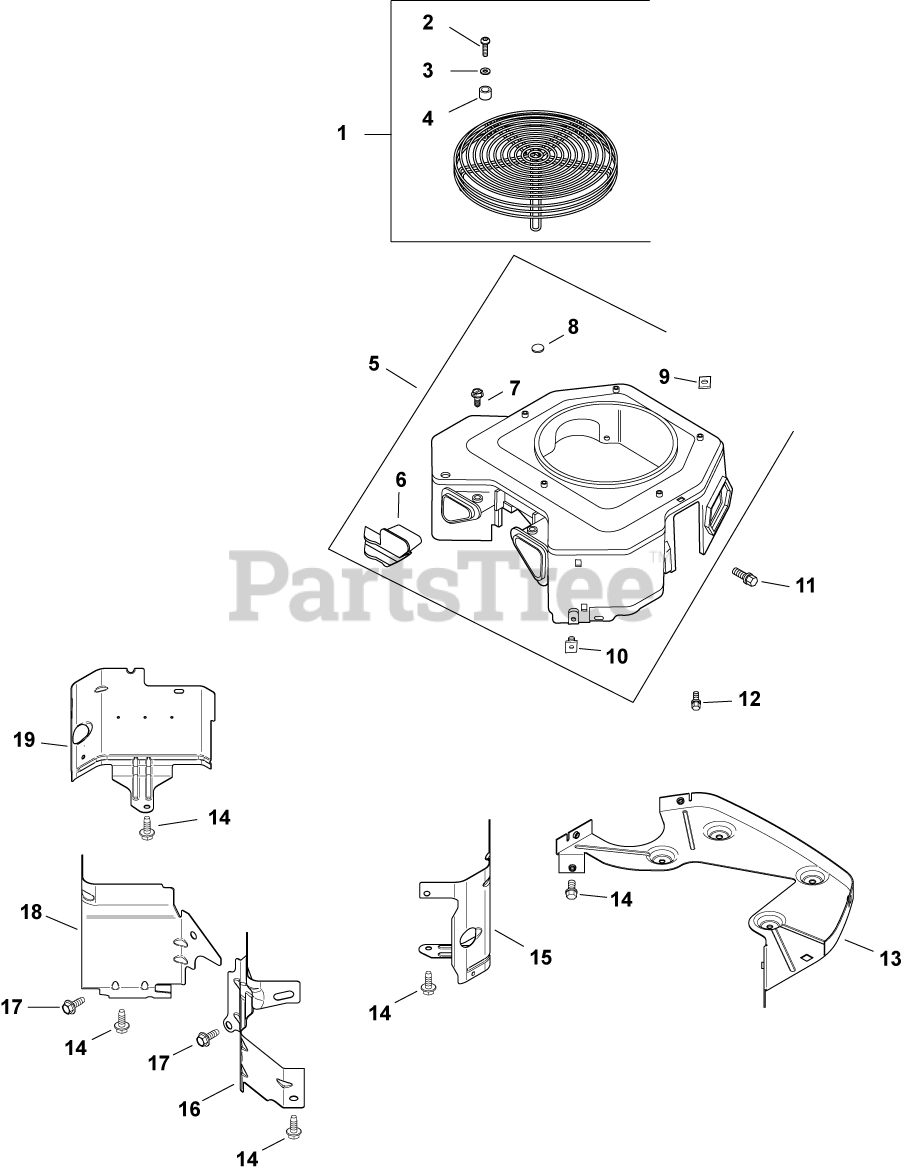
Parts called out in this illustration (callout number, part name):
1	KIT, GUARD
2	SCREW, PAN HEAD-USE 25 086 160-S
3	WASHER, FLAT 7/32"
4	SPACER USE 25 112 30-S
5	KIT, BLOWER HOUSING ASSEMBLY USE 24 027 494-S
6	COVER, BLOWER HOUSING-USE 24 096 119-S
7	SCREW, WSH HD TAP #8-18X1/2"
8	PLUG, BUTTON 9/16
9	NUT, PLASTIC (KM)-USE 25 100 37-S
10	NUT, PLASTIC
11	SCREW - USE M-545016-S
12	SCREW, FLG THD FRM M5X.8X20-(#25086399S)
13	PLATE, BACKING-USE 24 146 59-S
14	SCREW,FLG THD FRM M6X1.0X16-(#25086397S)
15	KIT, CYL BAFFEL #2 SIDE
16	BAFFLE, VALLEY #2 SIDE-USE 24 063 94-S
17	SCREW, FLG THD FRM M5X.8X10
18	BAFFLE, VALLEY (CV)-USE 24 063 93-S
19	KIT, CYL BAFFEL #1 SIDE
